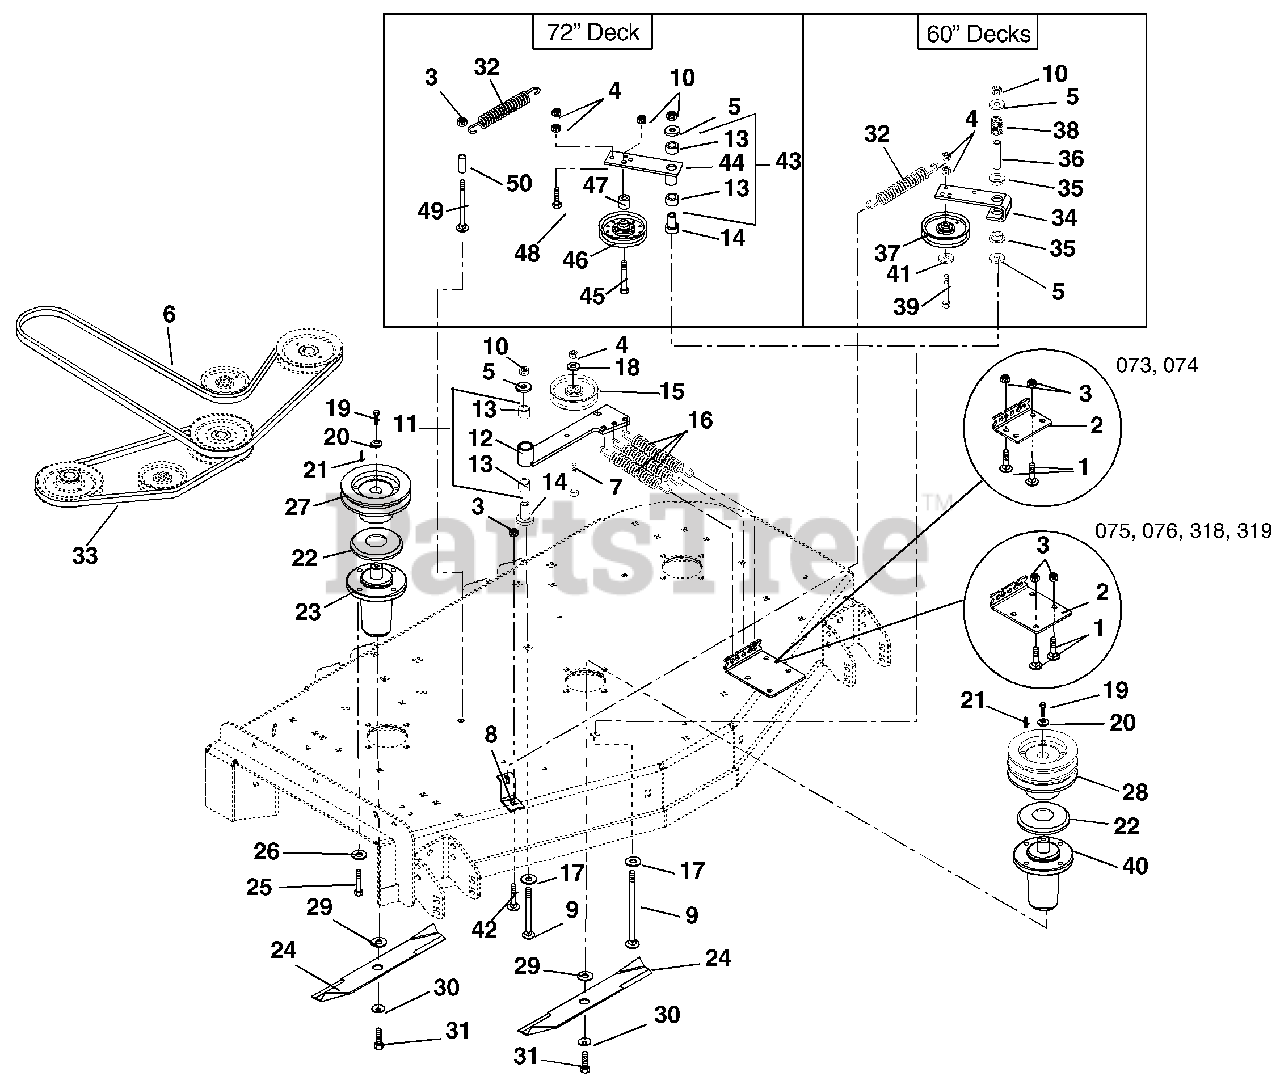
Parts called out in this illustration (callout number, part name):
1	Bolt, Round Head Square Neck .38-16 x .75 Grade 5
2	Bracket, Spring (075, 076, 318, 319)
2	Bracket, Short Spring (073, 074)
3	Nut, Locking Top Flange .38-16 (073, 075, 318, 319)
3	Nut, Locking Top Flange .38-16 (074, 076)
4	Nut, Locking Center .38-16
5	Washer, Flat Steel .531 x 1.25 x .10 (073, 075, 318, 319)
5	Washer, Flat Steel .531 x 1.25 x .10 (074, 076)
6	V-BELT, HB-WRAPPED (073, 075, 318, 319)
6	V-Belt, B-Section 58.25 x .625 (074, 076)
7	Bolt-Round Head Square Neck .38-16 x 2.75 Grade 5
8	Anchor, Spring
9	Bolt, Round Head Square Neck .50-13 x 3.50 Grade 5
10	Nut, Locking Top Flange .50-13 (073, 075, 318, 319)
10	Nut, Locking Top Flange .50-13 (074, 076)
11	Assembly-Deck Idler Pivot Arm (Contains Items 12 & 13)
12	Weldment, Deck Idler Pivot Arm
13	Bearing, 1.00 x 1.12 x .75
14	Bearing, Pedestal Powdered Metal (073, 075, 318, 319)
14	Bearing, Pedestal Powdered Metal (074, 076)
15	Idler, Flat 4.00 x .38 (2.32W)
16	Spring, Extension
17	Washer, Flat Steel .755 x 1.375 x .062
18	Washer, Flat Steel .375 x 1.125 x .065
19	Bolt, Hex .38-16 x 1.00 Grade 8
20	Washer, Cupped Serrated .375
21	Key, Square .25 x .25 x 1.00
22	Slinger, Dust
23	Assembly, Maintenance Free Spindle
24	Blade 60" Mower CE (318, 319)
24	Blade, Mower 60" Mulch (073, 075, 318, 319)
24	Blade, Mower-72" (24.50" LG) (074, 076)
24	Blade, Mower (073, 075)
24	Blade, Mower 72" Mulch (074, 076)
25	Bolt, Hex .38-16 x 1.00 Grade 5
26	Washer, Locking .38 x .094 Regular
27	Weldment, Spindle Sheave 6.00 (073, 075, 318, 319)
27	Weldment, Spindle Sheave (074, 076)
28	Sheave, Double (6.25) (073, 075, 318, 319)
28	Sheave, Double (7.25) (074, 076)
29	Washer, Flat .64 x 1.81 x .25
30	Washer, Bellville .63 x 1.625 x .14
31	Bolt, Hex .62-18 x 1.75 Grade 8
32	Spring, Extension (073, 075, 318, 319)
33	V-Belt B-Section 23.94 x .625 (073, 075, 318, 319)
33	V-Belt 5L-Section 49.97 x .672 (074, 076)
34	Arm, Idler Pivot (073, 075, 318, 319)
35	Bushing, Flange .762 x 1.00 x .58 x 1.48 Nylon (073, 075, 318, 319)
36	Spacer .56 x .75 x 2.44 Steel (073, 075, 318, 319)
37	V-Idler, 4.00 x .38 (073, 075, 318, 319)
38	Spring, Compression .085 x .80 x 1.00 (073, 075, 318, 319)
39	Bolt, Hex .38-16 x 2.25 Grade 5 (073, 075, 318, 319)
40	Spindle Assembly (Center)
41	Washer, Flat Steel .406 x .812 x .05 (073, 075, 318, 319)
42	Bolt, Round Head Square Neck .38-16 x 1.00 Grade 5
43	Assembly, Idler Arm Guard Drive
44	Weldment, Idler Arm Ground Drive (074, 076)
45	Bolt, Hex .38-16 x 6.00 Grade 5 (074, 076)
46	Idler, Flat Pulley 6.75 xz .51 (074, 076)
47	Spacer .513 x .748 x .62 (074, 076)
48	Bolt, Hex .38-16 x 1.25 Grade 5 (074, 076)
49	Bolt, Round Head Square Neck .38-16 x 2.75 Grade 5 (074, 076)
50	Spacer .38 x .625 x 1.50 (074, 076)
